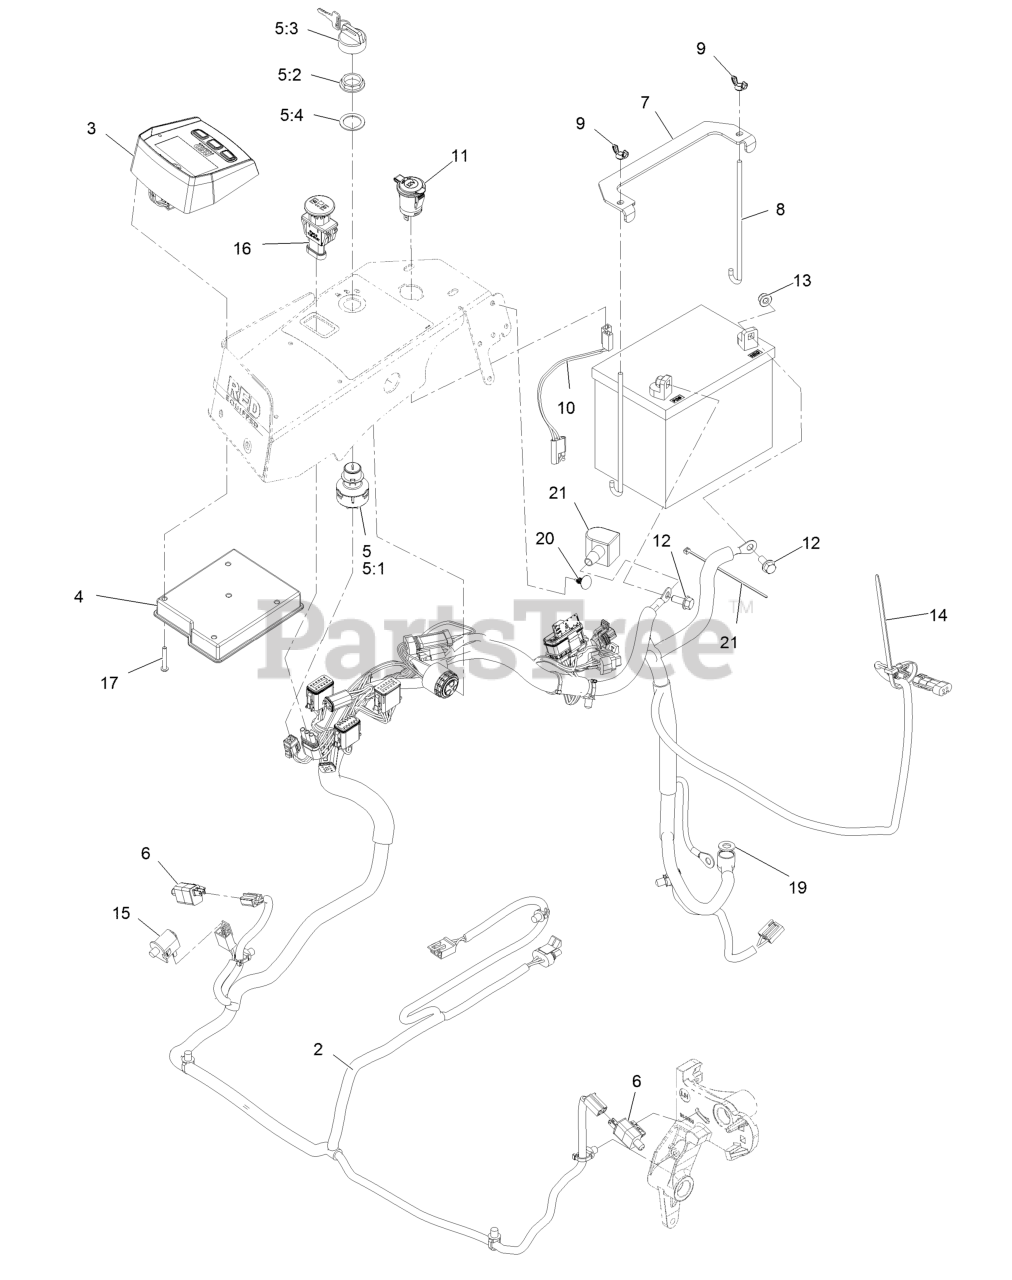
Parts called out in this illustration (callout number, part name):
2	Harness-Wire
3	Module, Ldu
4	Module-Mcu
5	Ignition Switch ASM
5:1	Switch-Ignition
5:2	Nut-Mounting
5:3	Ignition Key Set
5:4	Washer-Backup
7	Strap-Tie Down, Battery
8	Bolt-Holddown
9	Wingnut-Nyloc 1/4-20
10	Harness-Receptacle, 12V
11	Port-Power, 12V
12	Screw-HH Flg 5/16-18 X 3/4
13	Nut-Nyloc 5/16-18 Flg
14	Tie-Cable 7 15/16 (Large)
16	Switch-PTO, Sealed
17	Screw-PPH
19	Washer-3/8 SAE
20	Plug-Plastic
21	Tie-Cable
